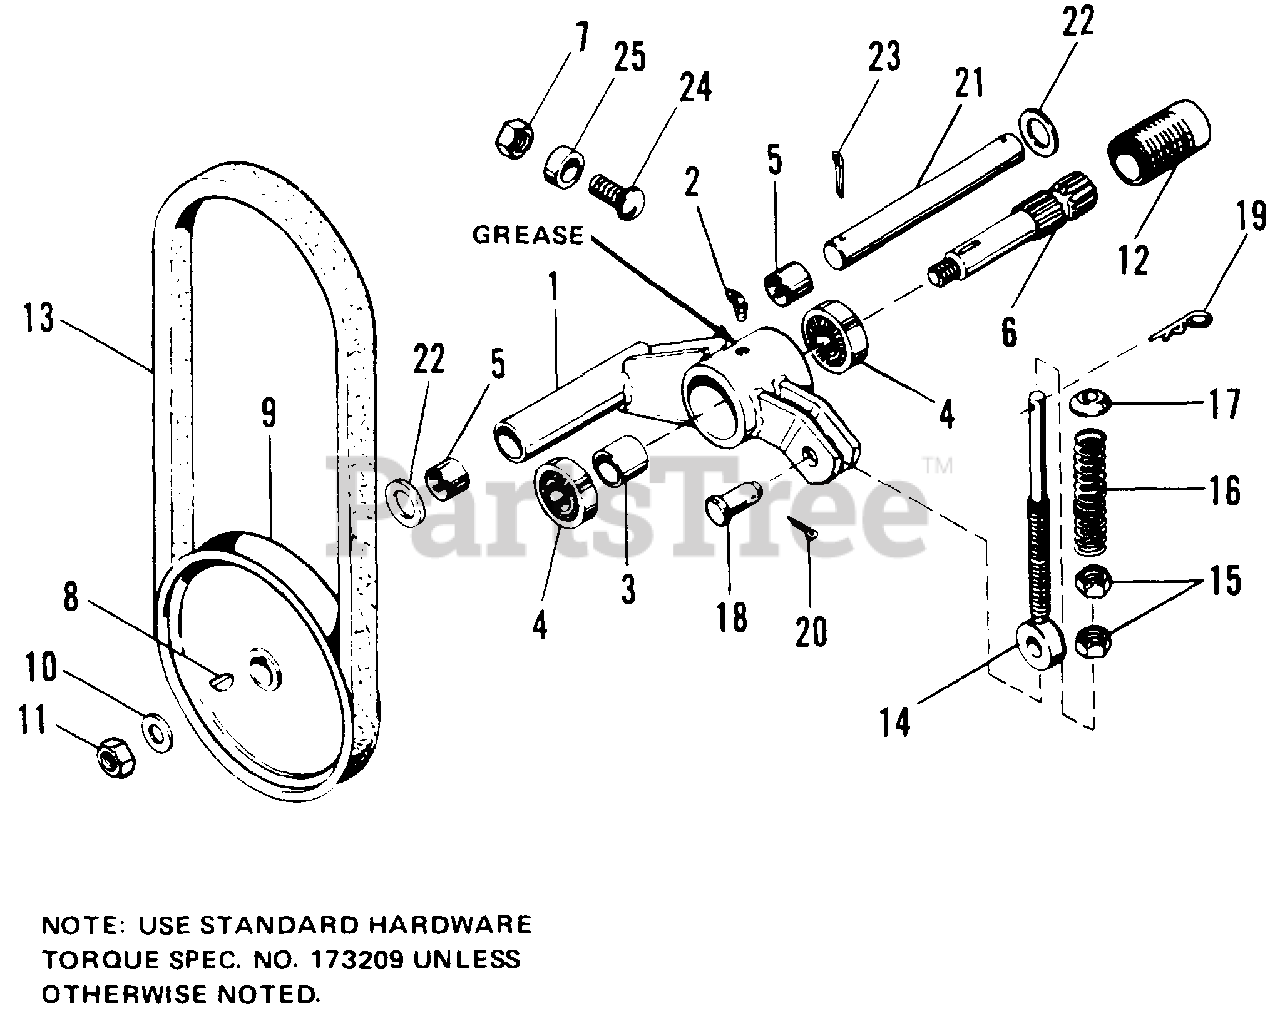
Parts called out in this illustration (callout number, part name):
1	HOUSING ASSY, w/Bearings
2	FITTING, Lube, Elbow 90, 1/4-20
6	SHAFT, PTO
7	NUT, Hex, Jam, Finished, 7/16-14
8	KEY, Hi Pro, 3/16 x 3/4
11	NUT, Hex, Full Lock, Jam, 1/2-13
12	GUARD, Crankshaft, Ext.
14	BOLT, Eye
15	NUT, Hex, Finished, 7/16-20
17	SPACER, Clutch
18	PIN, Yolk
19	CLIP, Spring
20	PIN, Cotter, 1/8 x 1
21	PIN, Clutch, Pivot
23	PIN, Cotter, 1/8 x 1-1/2
24	BOLT, Rd. Hd., Sq. Nk., 7/16-14 x 1
